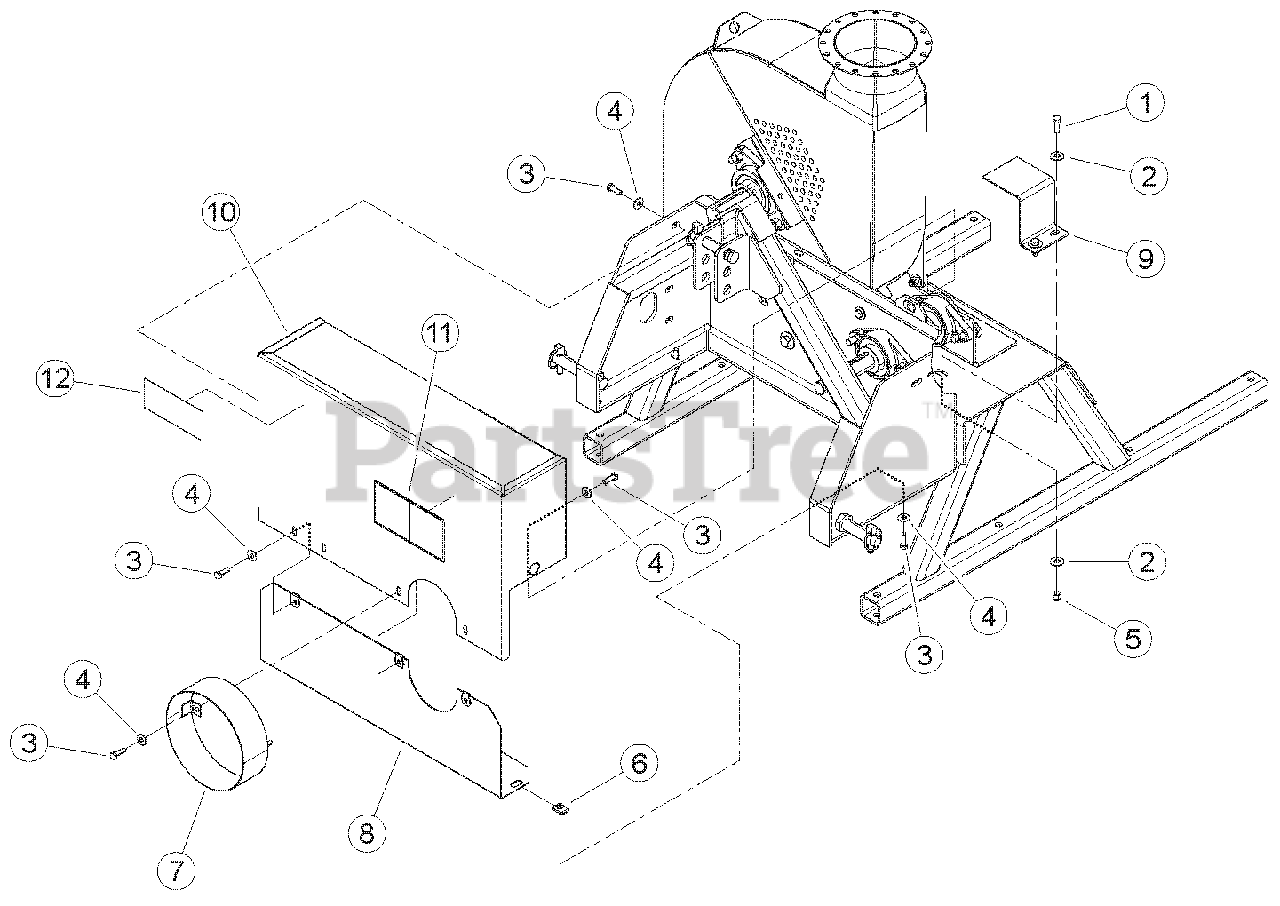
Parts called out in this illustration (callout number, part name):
1	DECAL, PTO DANGER ISO
2	DECAL, MUTILINGUAL MANUAL
3	BOLT, 3/8 X 1 HEX HD GR5 ZP
4	WASHER, 3/8 FLAT ZP
5	BOLT, 5/16 X 1 HHCS GR5 NC ZP
6	WASHER, 5/16 FLAT ZP
7	NUT, 3/8 NE NYLOCK ZP
8	NUT, 5/16-18 TINNERMAN U-TYPE
9	WELDMENT, JOINT SHIELD
10	WELDMENT, UPPER BELT GUARD
11	GUARD, LOWER BELT
12	COVER, JACKSHAFT
